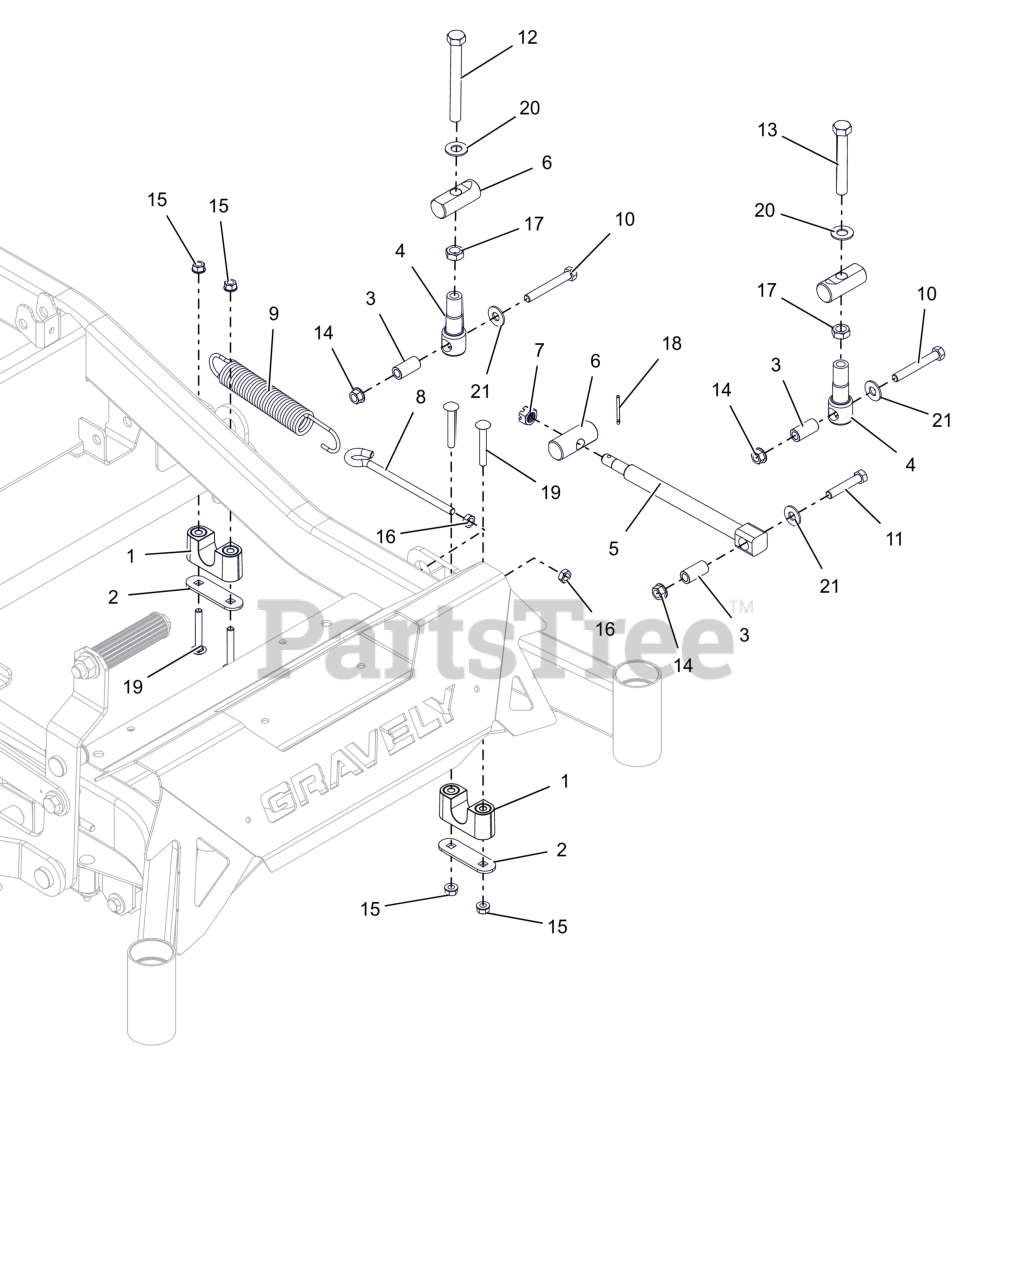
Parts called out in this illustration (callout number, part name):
1	ASM-BUSHING, DECK LIFT
2	PLATE, BEARING SUPPORT
3	SPACER, DECK LEVELING
4	LINK, DECK LIFT FORMED
5	DRAG,LINK-HD
6	PIN, DECK LIFT
7	NUT-SL .50-13
8	BOLT,.38-16 X 5.25-.62 DIA EYE
9	SG-TENS .162X1.25X8.25 WLD 25
10	BLT, HEX .38-16X2.75 G8 ZCC
11	BLT,HEX .38-16X2.00 G5 ZCC
12	BLT, HEX .50-13X4.50F G8 ZCC
13	BLT, HEX 0.5-13X3.5F GR5 ZCC
14	NUT-LK-TOP-FLG .38-16 ZC120
15	NUT,LK-CTR-FLG .31-18 GF ZCC
16	NUT-JAM .375-16 G2 ZCC
17	NUT-JAM .500-13 G2 ZCC
18	PIN,CTR.12X1.25EXTPRSQCT ZC120
19	BLT, RHSSN.31-18X2.25 G5 ZCC
20	WSHR, FLT .557X1.040X.102 ZCC
21	WSHR,FLT .438X1.00X.083 ZCC
